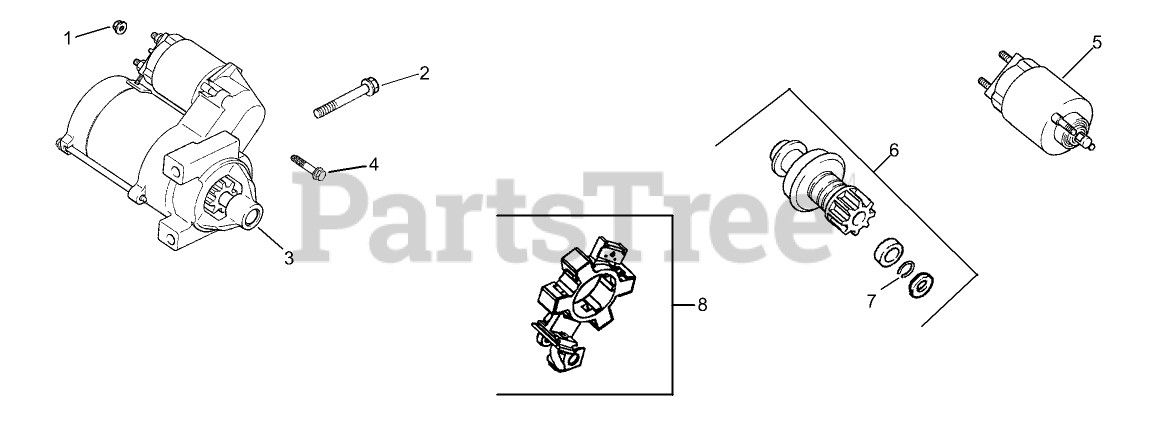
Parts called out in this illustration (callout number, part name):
1	NUT-FLANGE (M8X1.25)
2	SCREW-FLG (M8X1.25X80)
3	Starter, solenoid shift ASM (Incl. Ref. #4-7)
4	SCREW-TORX HEAD, EXTERNAL
5	Kit, solenoid (Incl. Ref. #4)
6	Kit, pinion drive (Incl. Ref. #7)
7	RING-RETAINING
8	BRUSH HOLDER KIT
